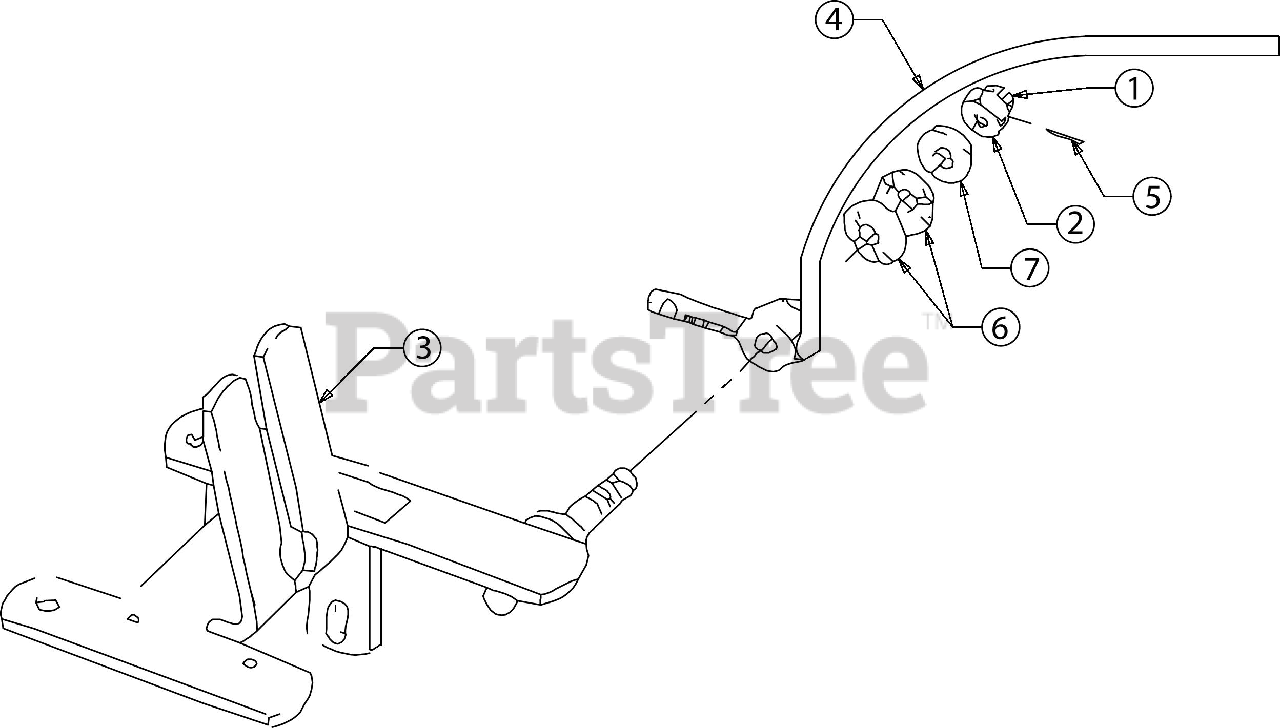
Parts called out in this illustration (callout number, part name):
1	HEX NUT
2	FLAT WASHER .510 X 1.000 X .125
3	SHIFT LEVER BR
4	WHEEL SPEED LEVER
5	SPRING PIN
6	WASHER-#1.97X1X.11
7	WASHER-#SHOULDER
